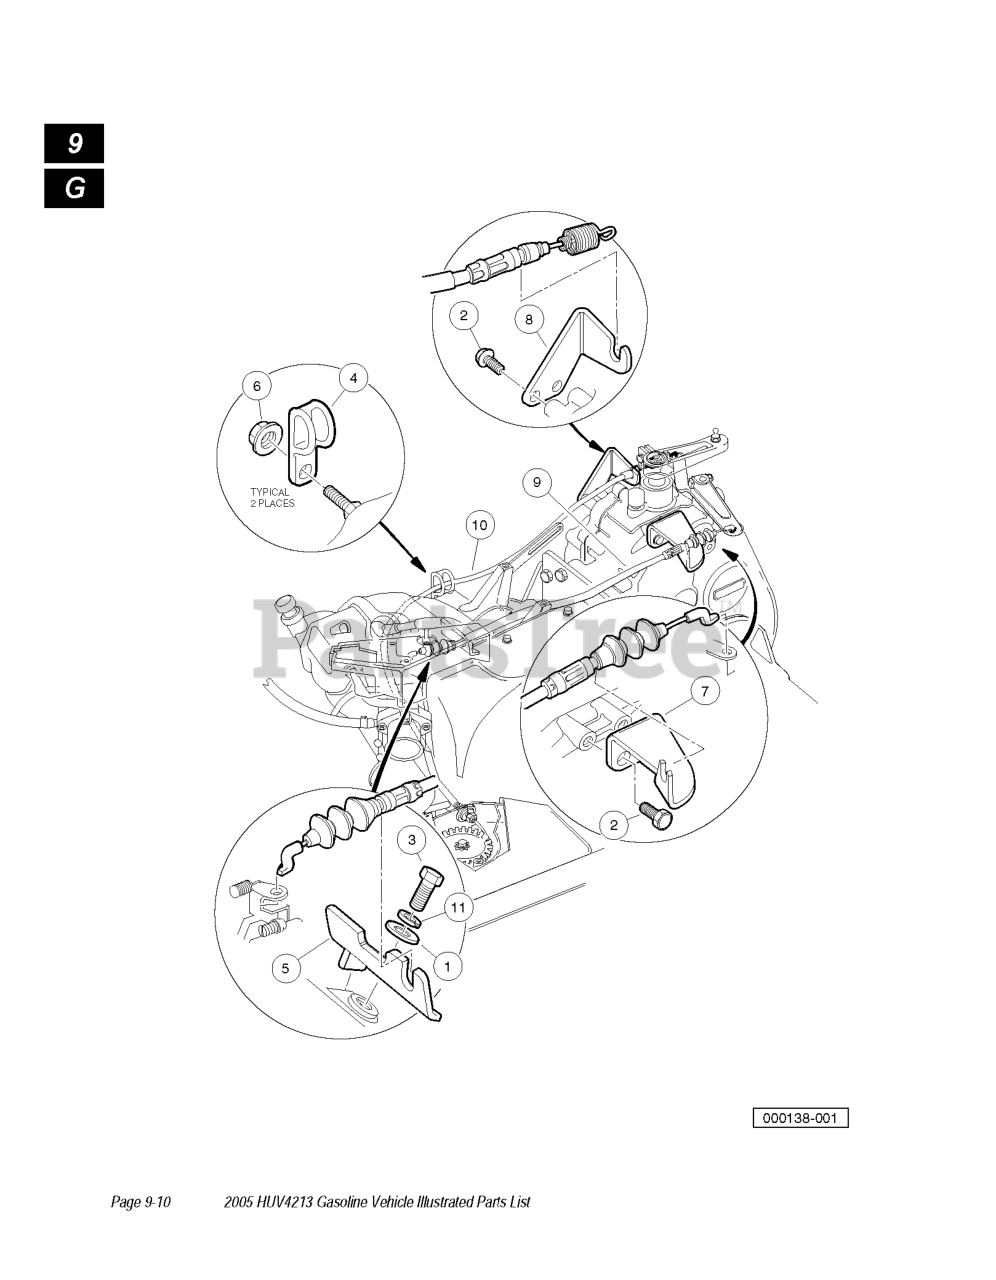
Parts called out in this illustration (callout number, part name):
1	WASHER, 5/16 FLAT
2	SCREW HX TYP TT
3	SCREW, M8-125 X 22 HEX GR.8.8
5	BRACKET, GOVERNOR CABLE ENGINE
7	BRKT, REAR GOV CABLE SNAP-IN
8	BRKT, REAR ACC CABLE SNAP-IN
9	CABLE, GOV, SNAP-IN
10	CABLE, ACC, SNAP-IN
11	LOCKWASHER, 5/16 SPLIT
